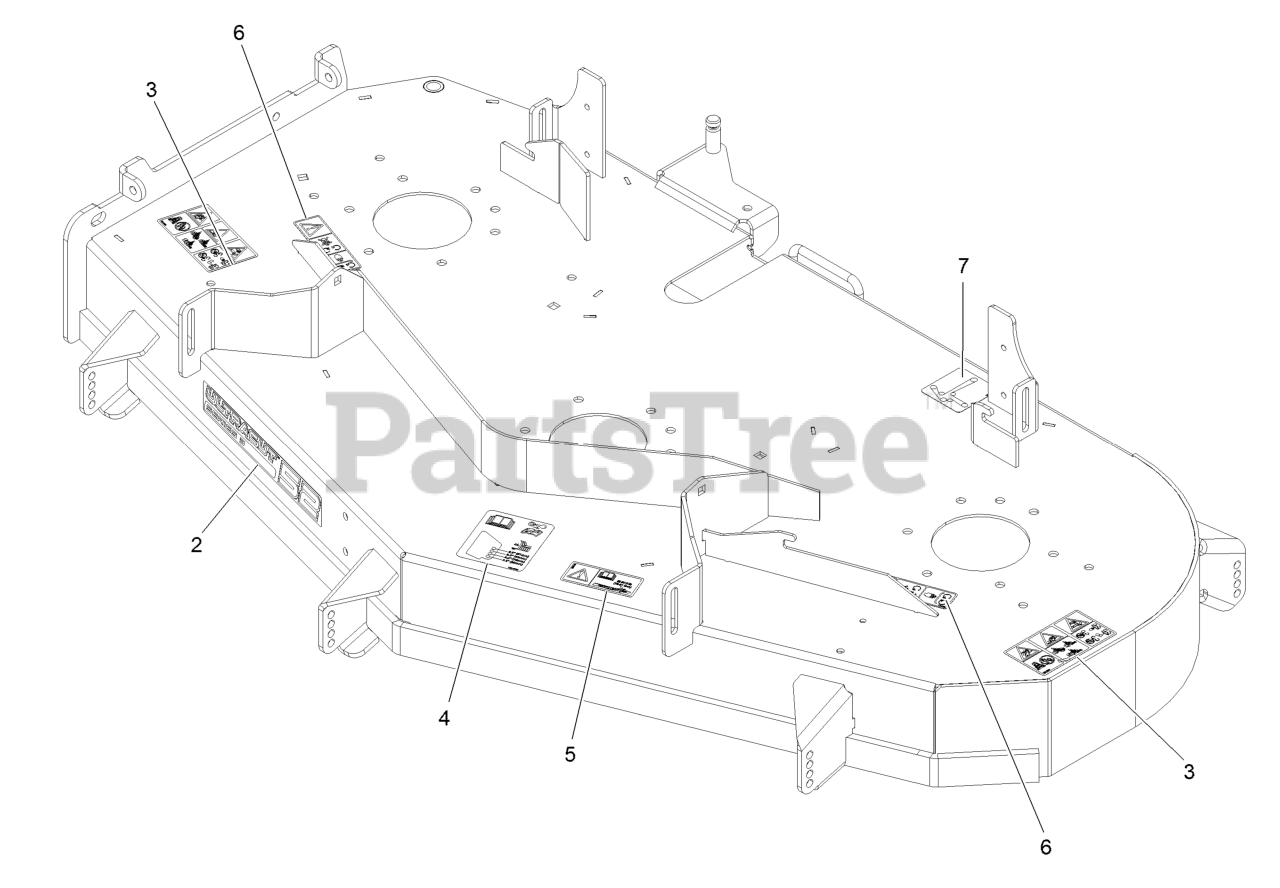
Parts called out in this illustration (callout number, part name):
2	Decal-Ultracut 52 Series 3
3	Decal-Danger Thrown Objects
4	Decal-Roller, Anti-Scalp
5	Decal-Bolt Torque
6	Decal-Missing, Cover
7	Decal-Routing, Belt
